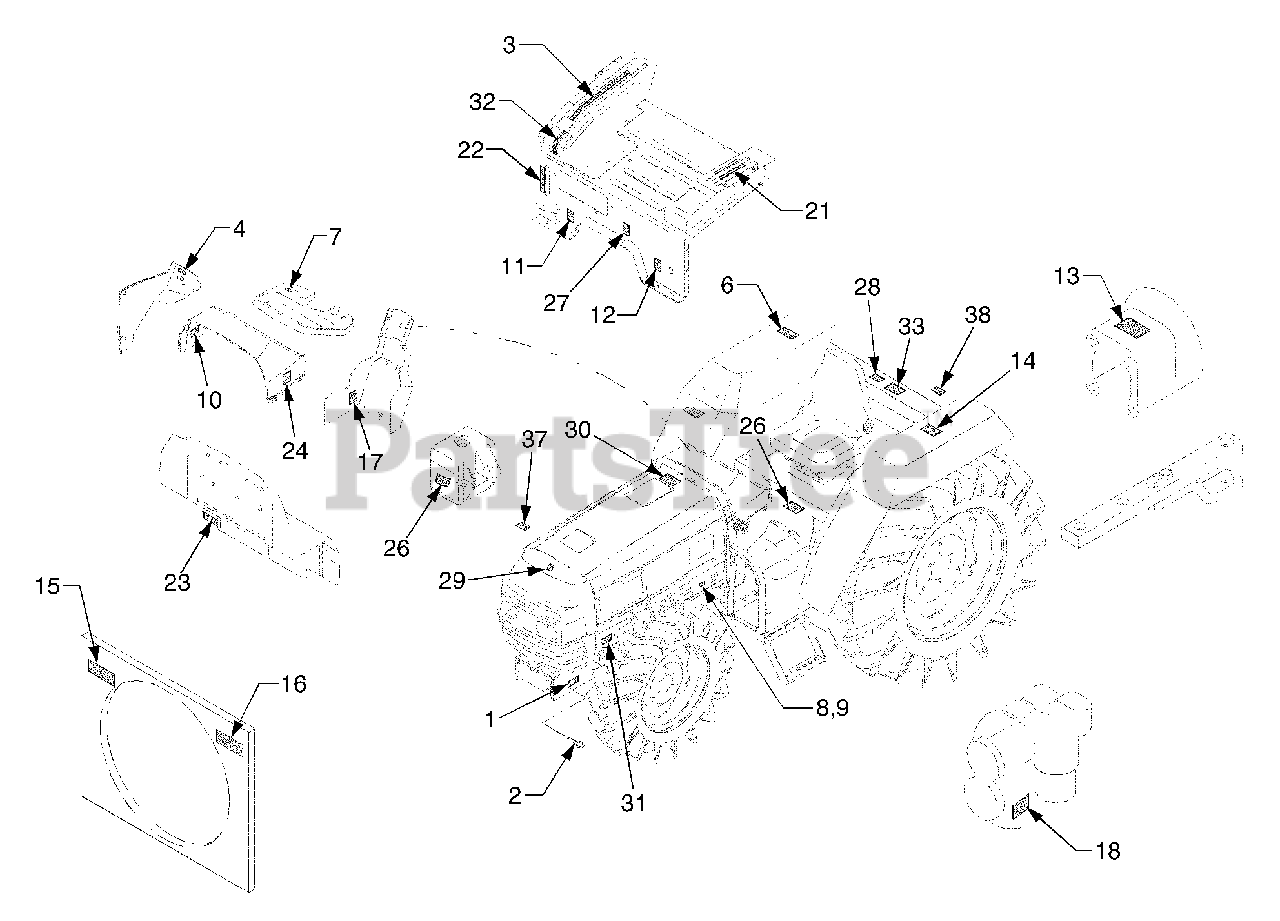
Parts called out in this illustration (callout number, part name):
1	Label, Product
3	Label, Position
4	Label, Start S/W
5	Label, Cartridge
6	Label, Safety
7	Label, PTO Clutch
8	Label, Reminder (RH)
9	Label, Reminder (LH)
10	Label, Parking Brake
11	Label, Diff. Lock
12	Label, Front Wheel
13	Label, PTO Caution
14	Label, Rops Caution
15	Label, Caution(Fan)
16	Label, Muffler
17	Label, Caution
18	Label, Hyd. Block
21	Label, Hi-Low
22	Label, Mid PTO
23	Label, Fuel Filter
24	Label, Caution
26	Label, Cooling Water
27	Label, Speed Control
28	Label, Oil Fill
29	Label, Front Grill
30	Label, Fuel Caution
31	Label, Muffler Caution
32	Label, Adjusting Lever
33	Label, Coupler Socket
37	Label, Radiator
38	Label, Implement Caution
